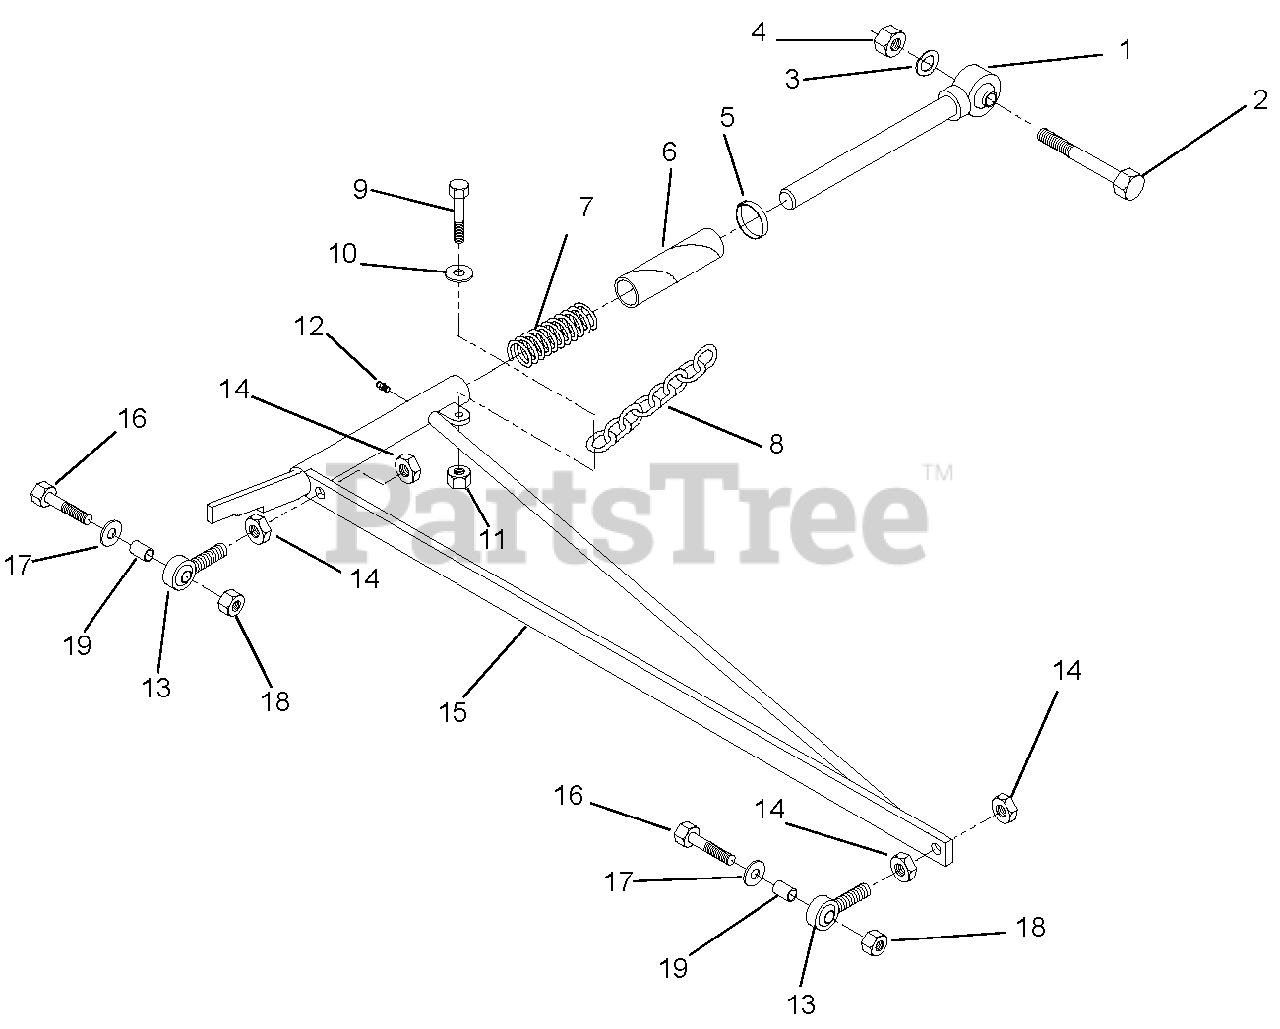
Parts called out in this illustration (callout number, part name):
1	Weldment, Telescoping Arm Shaft
2	Bolt, Pivot
3	Washer, Lock .75 CP
4	Nut, Hex .75-10
5	Clamp, Pinch
6	Sleeve, Telescoping Arm
7	Spring, Compression
8	Chain, 8-Link
9	Cap Screw, Hex Head .312-18 x 1.5
10	Washer, Flat .312 SAE
11	Nut, Hex .312-18
12	Fitting, Grease
13	Rod End .625 Bore, Right Hand Thread
14	Nut, Jam .625-18 NF
15	Weldment, Stabilizer Arm, Left Hand
16	Cap Screw, Hex Head .50-13 x 2
17	Washer, Flat .50 SAE
18	Nut, Hex .50-13 CP Nylock
19	Bushing, Adapter
